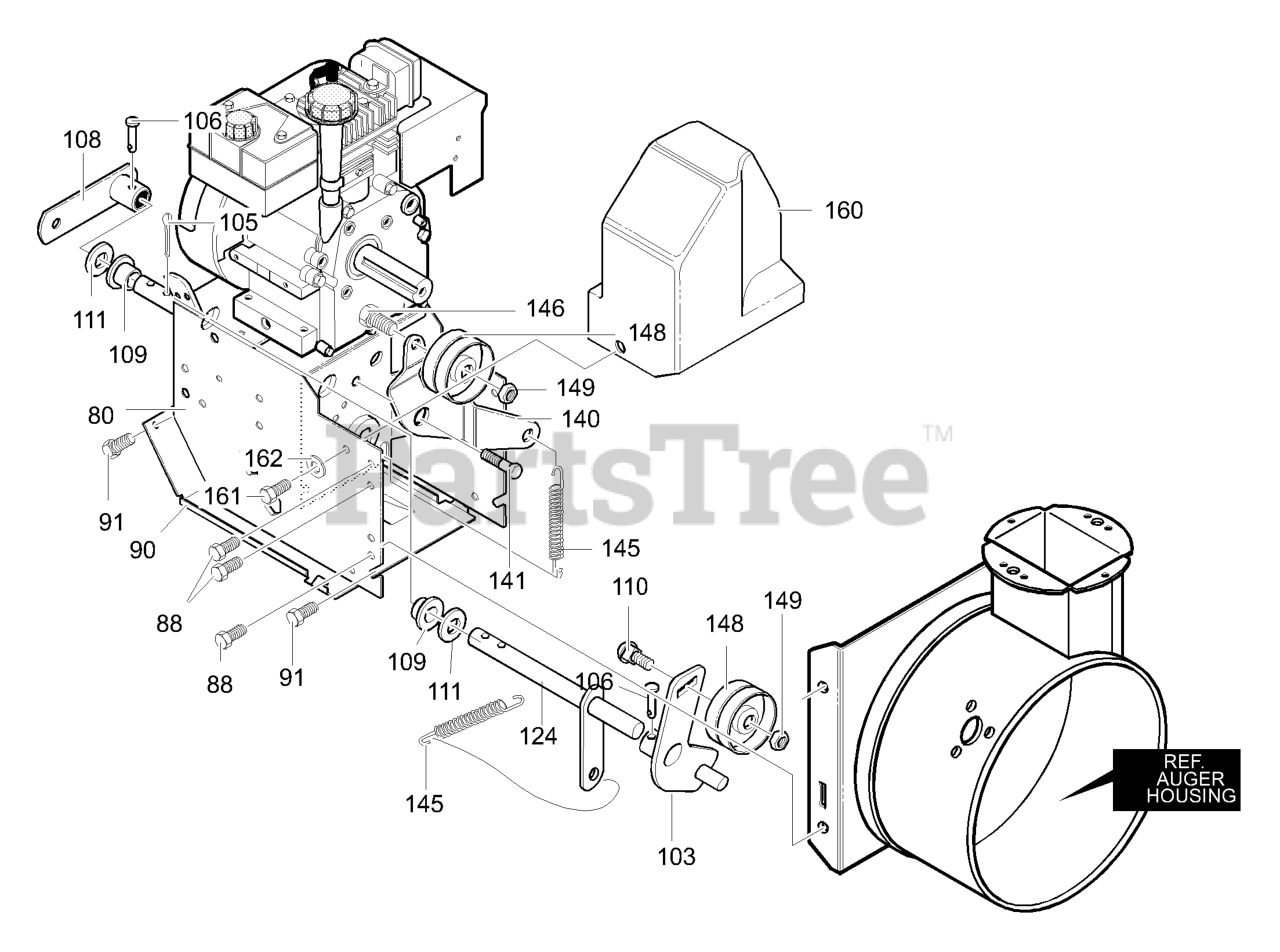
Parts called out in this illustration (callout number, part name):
80	FRAME, ASSY
88	SCREW, 5/16-18 x 0.50
90	COVER, BOTTOM
91	SCREW, 1/4-20X.63 WAHHTAP
103	ASSY., IDLER
105	HAIR PIN
106	CLIP, KLIK
108	ASSY.,SPRING ATTACH WHEEL
109	BEARING, FLANGE
110	BOLT 3/8-16X1.25
111	FLATWASHER
140	LEVER, IDLER ARM TRACTION
141	BOLT, 5/16-18
145	SPRING, IDLER TRACTION DR
146	SCREW, 3/8-16 x 1.25
148	PULLEY, IDLER
149	NUT, 3/8-16 CTRLKJAM
160	BELT COVER
161	SCREW, 1/4-20X.63 WAHHTAP
162	FLATWASHER, .281X.63X.065
